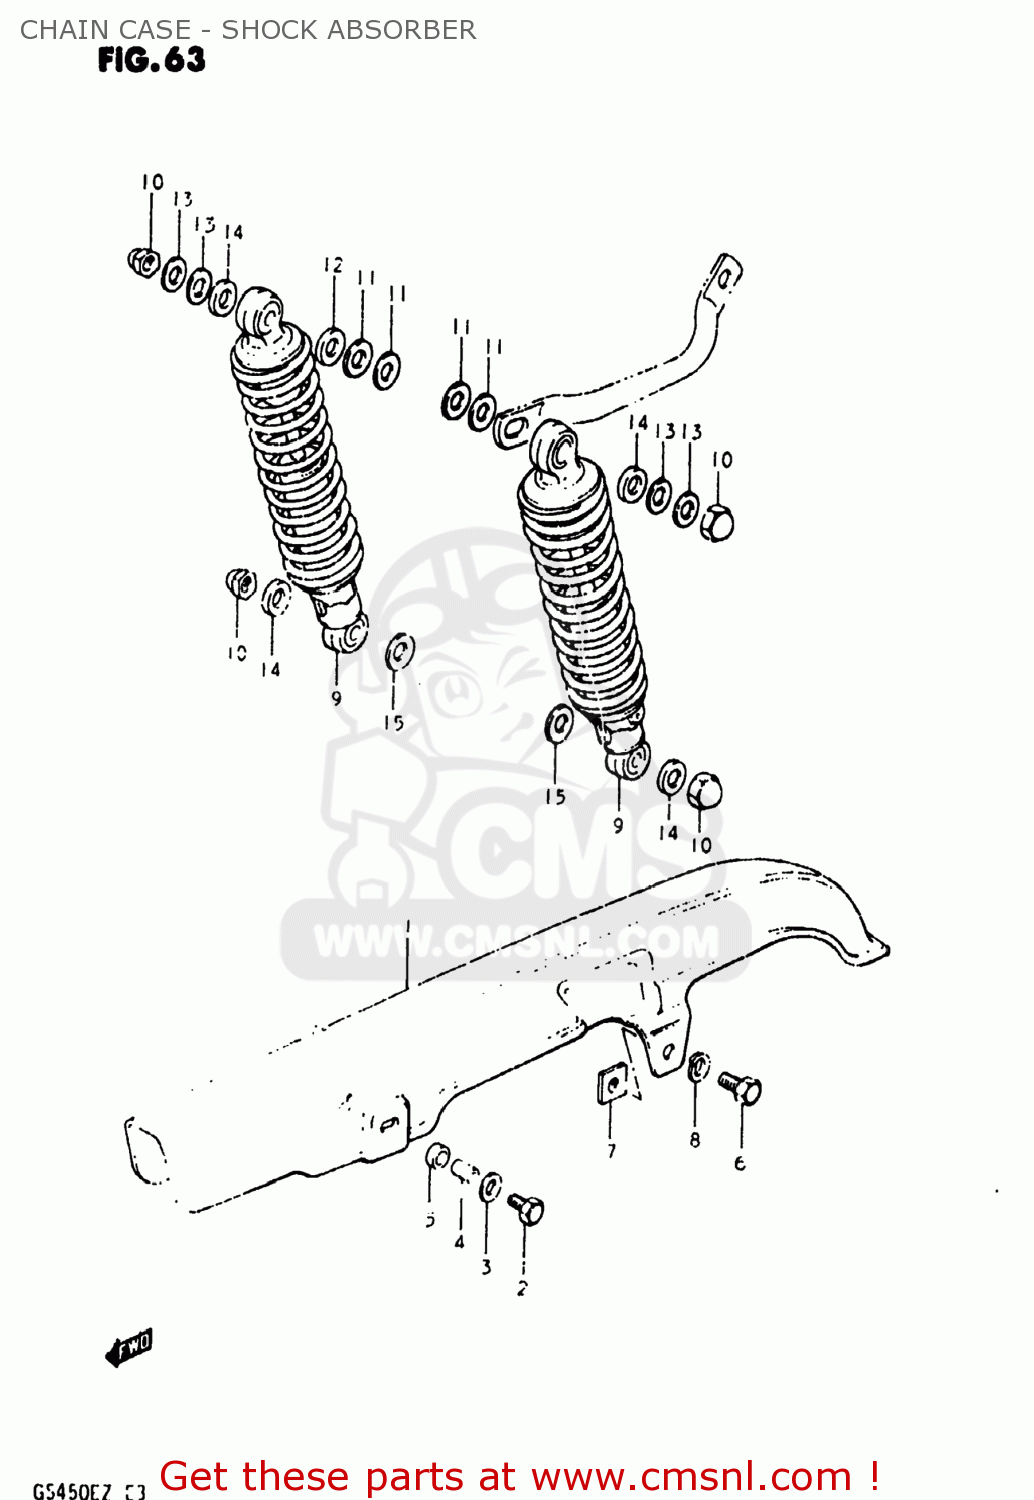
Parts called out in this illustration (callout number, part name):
1	CASE,CHAIN
2	BOLT
3	WASHER(6.5X18X1)
4	SPACER (6.1X8X5.2)
5	CUSHION
6	BOLT, UPPER
7	NUT,CHAIN CASE RR
8	LOCK WASHER
9	ABSORBER ASSEMBLY,REAR SHOCK
10	NUT, LOWER LH
11	WASHER
12	WASHER (12.5X24X3.2)
13	WASHER
14	WASHER(10.5X24X3.2)
15	WASHER (12.5X24X1.6)
